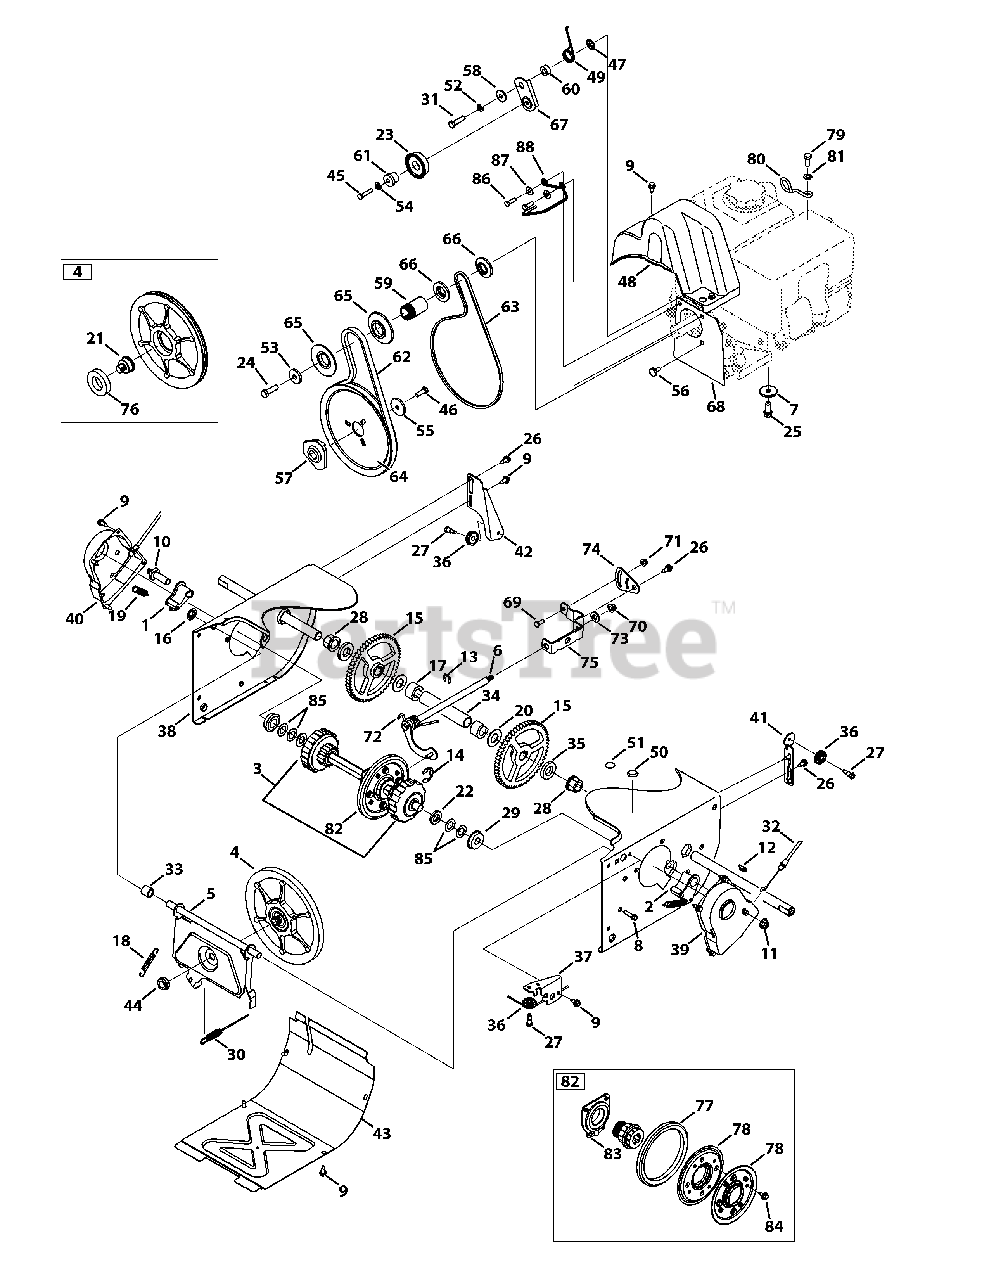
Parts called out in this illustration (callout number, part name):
1	Dogg Assembly, RH
2	Dogg Assembly, LH
3	Drive Shaft Assembly
4	Friction Wheel Disc Assembly
5	Friction Wheel Support
6	Rod Shift Assembly
7	Washer, Flat, .38 x 1.38
8	Screw, 1/4-20 x 1.000
9	Screw, 1/4-20 x .625
10	Actuator Shaft
11	Nut, Flangelock, 3/8-16
12	Hi-Pro Key, 3/16 x 3/4 DIA
14	Retainer Ring
16	Nut, Speed, .500
17	Spacer, .76 x .75
18	Extension Spring, .380 x 2.500
19	Extension Spring, .500 x 1.71
20	Washer, Flat, .76 x 1.49
21	Friction Pin, Disc Bearing
22	Spacer, .68 ID x 1.25 OD x .20
23	Pulley Assembly
24	Hex Head Screw, 3/8-24 x 1.25
25	Taptite Sems Screw, 3/8-16 x 1.000
26	Screw, Shoulder, .368 x .113 x 1/4-20
27	C Screw, Shoulder, .340 x .335 x 1/4-28
28	Hex Flange Bearing, .75 ID
29	Ball Bearing, 17 x 40 x 12
30	Drive Clutch Cable
31	Hex Head Screw, 5/16-24 x 1.25
32	Steering Cable
33	Spacer, .508 x .75
34	Axle Support Tube
35	Spacer, Axle
36	Roller Cable
37	Auger Cable Guide Bracket
38	Wheel Drive Frame
39	Shaft Retainer, LH
40	Shaft Retainer, RH
41	Auger Clutch Cable Guide Bracket
42	Drive Clutch Cable Guide Bracket
44	Nut, Flange, 5/8-18
45	Taptite Screw, 1/4-20 x 1.250
46	Hex Head Screw, 5/16-24 x .875
47	Nut, Push-On, .25 DIA
48	Belt Cover, 4-Way lrg. block
49	Spring, Torsion, .850 x .333
50	Plug, 3/8 ID
51	Plug, 1/2 ID
52	Washer, Lock, 5/16
53	Washer, Flat, .45 x 1.5
54	Washer, Lock, 1/4
55	Washer, Flat, .34 x 1.50
56	Screw, Shoulder
57	Pulley Adapter, .75 DIA
58	Spacer, Shoulder, .3175 x .500
59	Spacer, .875 x 1.185
60	Spacer, .340 x .750
61	Spacer, Shoulder, .260 x .785
62	Auger Drive Belt, 4-Way lrg. block
63	V Belt, 3L x 36.64"
64	Auger Pulley, 8.1 x .5
65	Pulley, Half, 4L-V x 2.600
66	Pulley, Half, 3/8-V x 2.2
67	Drive Idler Bracket
68	Cover Plate, 4-Way lrg. block
69	Hex Head Screw, 1/4-20 x .620
70	Nut, Flangelock, 5/16-18
71	Nut, Flangelock, 1/4-20
72	Spring, Torsion, .750 x .968
73	Washer, Flat, .469 x .875 x .105
74	Speed Selector Pivot Bracket
75	Speed Selector Shift Bracket
76	Ball Bearing, 30 x 55 x 13
77	Friction Wheel, 5.5 OD
78	Friction Wheel Plate
79	Hex Head Screw, 1.25 x 20
80	Cable Guide
81	Washer, Flat, .330 x .630
82	Friction Wheel Assembly
83	Bearing Assembly, Friction Wheel
84	Screw, 5/16-18 x .750
85	Flat Washer, .67 x 1.174 x .02
86	Hex Head Screw, 5/16-24 x 1.00
87	Washer, Flat, .349 x .879
88	Belt Guide
